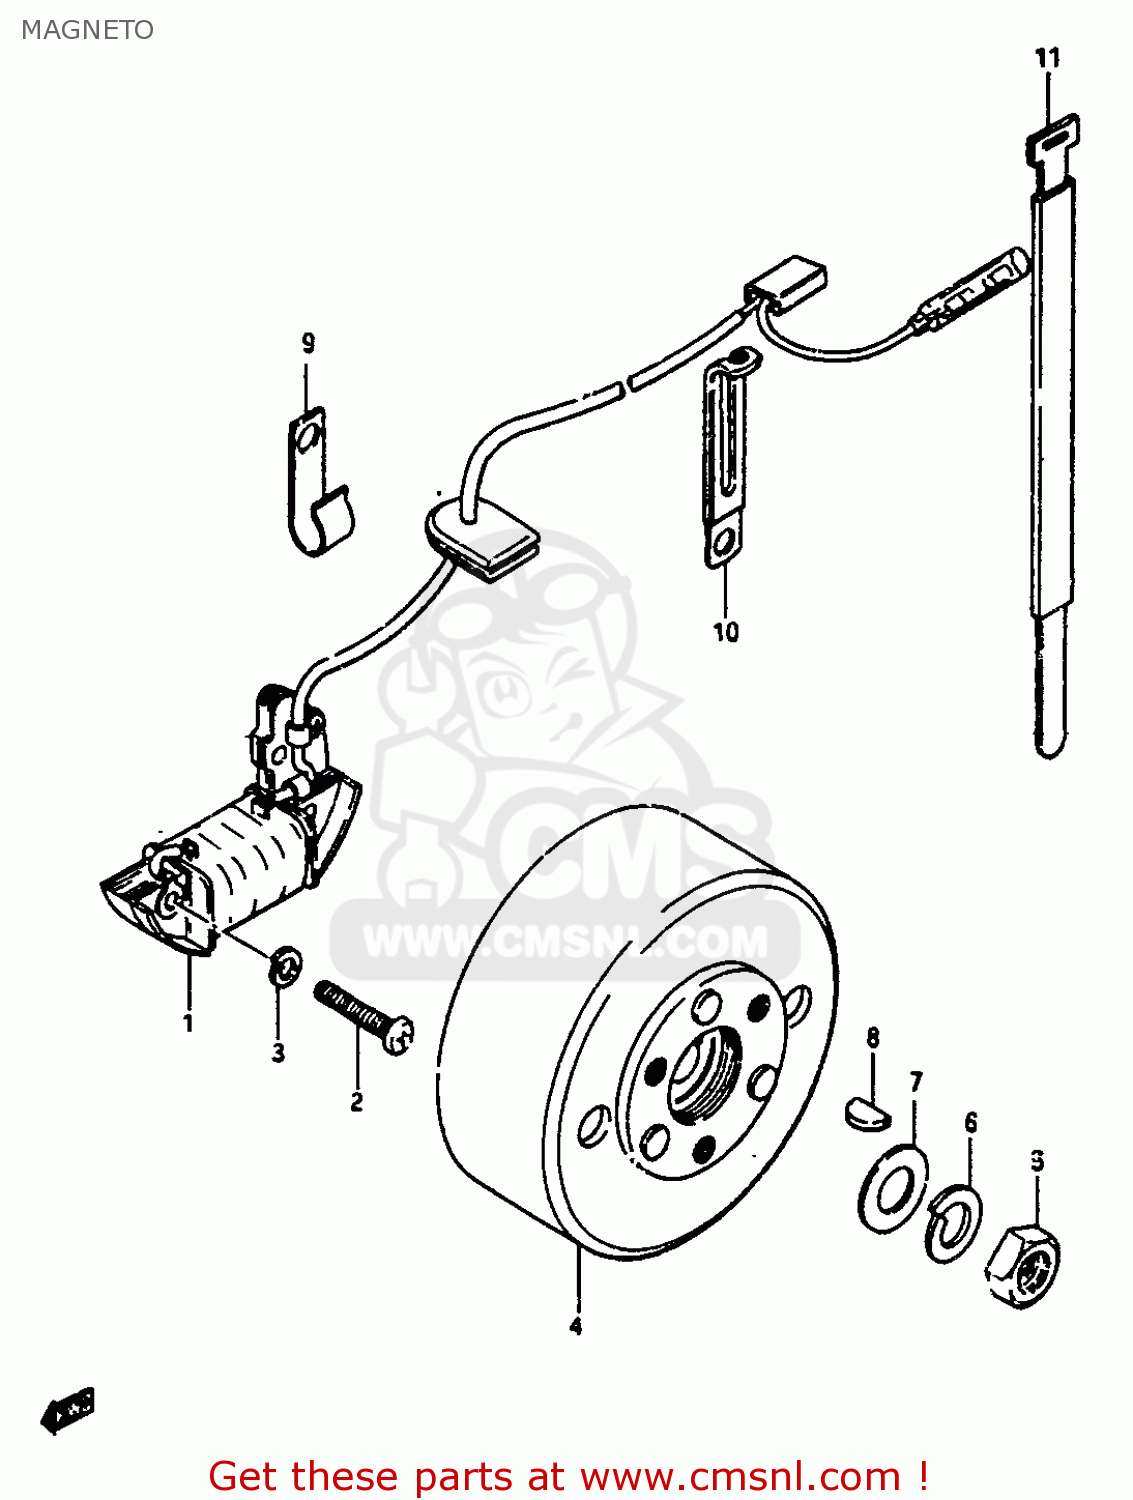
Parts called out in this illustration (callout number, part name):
1	STATOR ASSEMBLY
2	SCREW 4X25
3	WASHER,LOCK 4M
4	ROTOR ASSY
5	NUT
6	WASHER,LOCK,10
7	WASHER
8	KEY
9	CLAMP
10	CLAMP L:35
11	CLAMP
